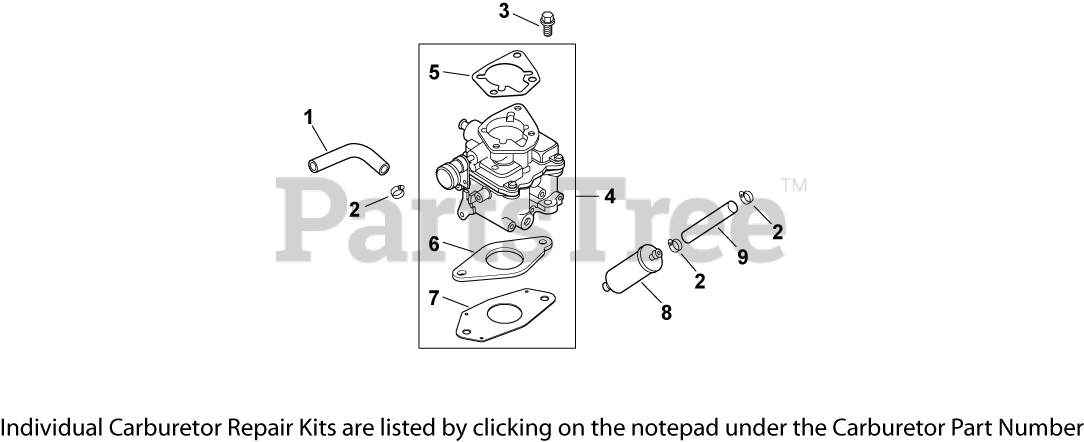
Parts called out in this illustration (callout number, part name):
1	HOSE,LW PERM.FUEL 24.00"-USE 25 111 81-S
2	CLAMP, HOSE (KM)-USE 25 237 31-S
3	SCREW, FLG M6X1.0X25
4	KIT, CARBURETOR W/GASKET KSF
5	GASKET, AIR CLEANER BASE
6	GASKET, CARBURETOR
7	GASKET, CARBURETOR
8	FILTER, FUEL
9	LINE, FUEL 11"
